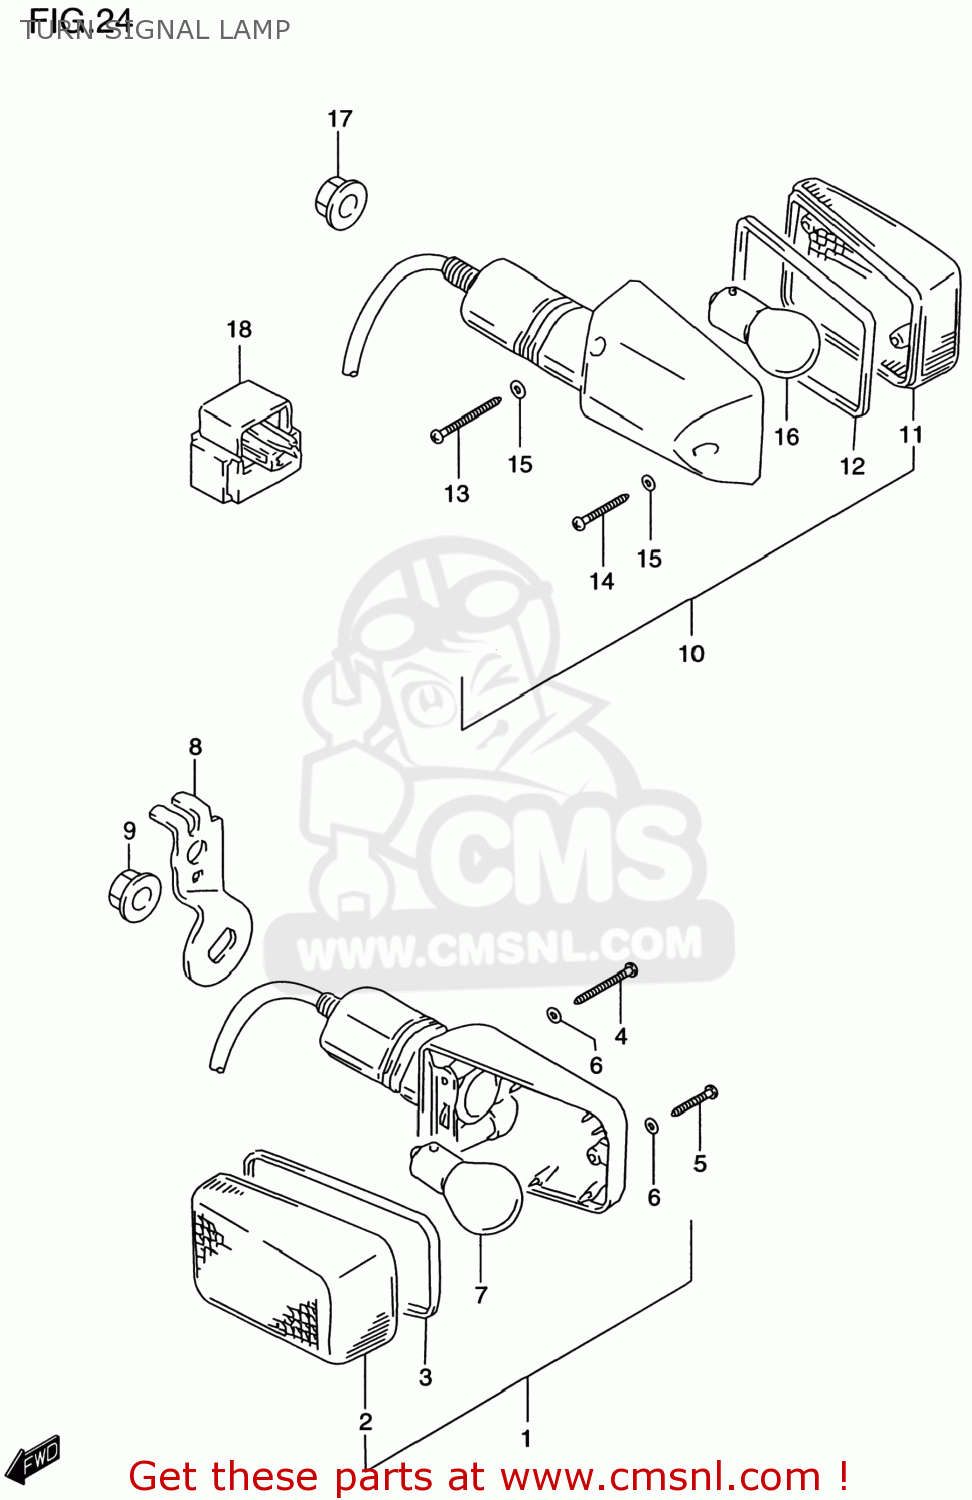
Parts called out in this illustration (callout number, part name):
1	LAMP ASSY,FR TURN SIGNAL
2	LENS
3	GASKET (NAS)
4	SCREW(3X30)
5	SCREW
6	GASKET (NAS)
7	BULB(12V21W)
8	BRACKET,FR TURNSIGNAL,R
9	NUT
10	LAMP ASSY,RR TURNSIGNAL,R
11	LENS
12	GASKET (NAS)
13	SCREW(3X30)
14	SCREW
15	GASKET (NAS)
16	BULB(12V21W)
17	NUT
18	RELAY ASSY
